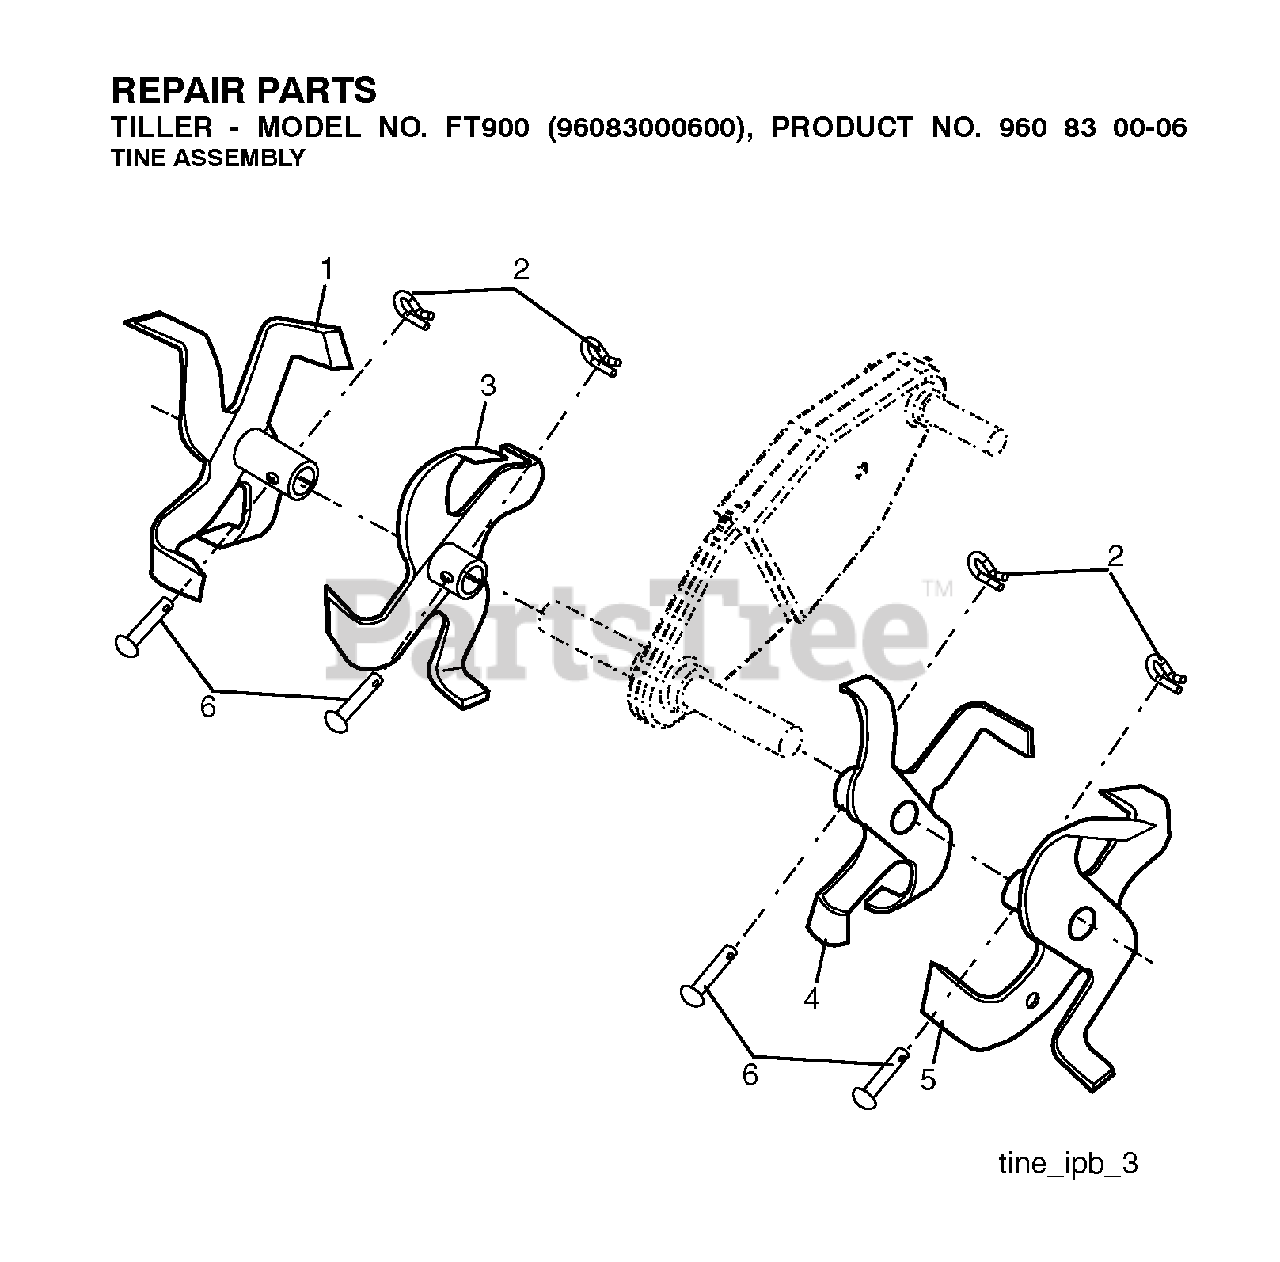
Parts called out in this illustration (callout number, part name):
1	RP TINE
2	SPRING RETAINER
3	RP TINE
4	RP TINE
5	RP TINE
